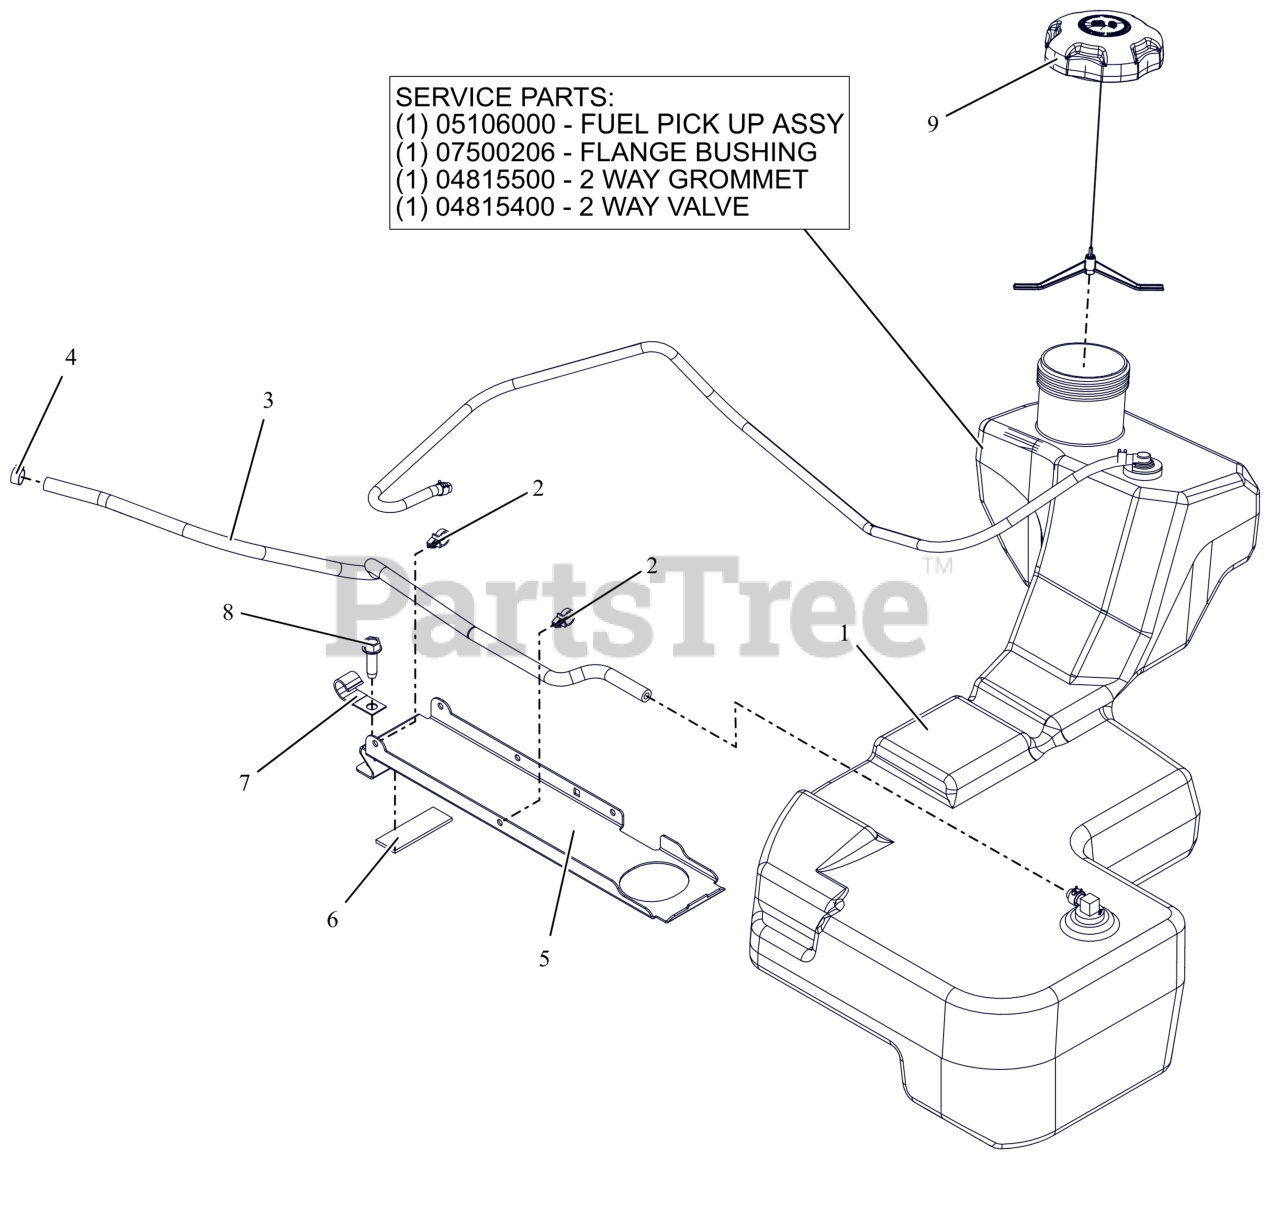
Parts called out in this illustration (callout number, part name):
1	ASM, FUEL TANK-HD
1	ASM, HD FUEL PICK-UP
1	BSHG-FLG .375X1.062X.625 NITR
1	GROMMET, 2-WAY
1	VALVE, 2-WAY
2	ROUTING CLIP (1/2" ID)
3	HOSE, .25 LOW-PERM BULK GAS
4	CLAMP, FUEL LINE
5	BRKT, FUEL TANK HOLD DOWN
6	PAD,RBR 1.0"X3.0" W/ADHESIVE
7	J-CLAMP
8	SCR,TAP .375-16X1.25HWH TR ZCC
9	CAP, FUEL - 3.50 RATCHET INLET VENT
